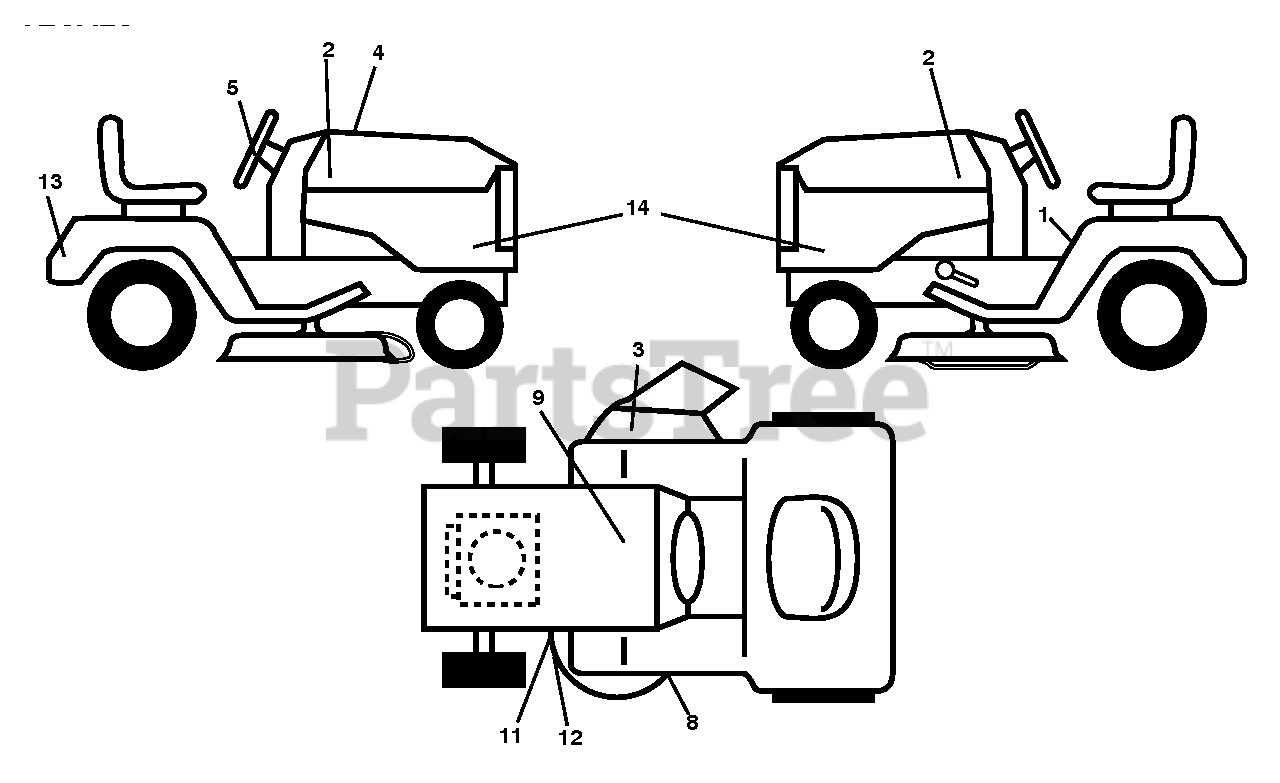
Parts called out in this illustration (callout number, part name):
1	DECAL.FENDER.WARNING.ENGLISH
2	DECAL.POULAN PRO.2015
3	DECAL, DECK DEFLECTOR, WARNING
4	DECAL DECAL.RPL.KH.KT7.TGW.54.
5	DECAL.STRWHL.BLK.2014.PPRO
8	DECAL.MOWER.SCH.48/54.PREM
9	DECAL BTRY SYMBOLS
11	DECAL.MOWER.CAUTION.TENSION.AR
12	DECAL.PPRO.10YRDECKWAR.POP
13	DECAL.REARFNDR.POULAN PRO.2015
14	DECAL.SDPNL.PB24VA54.BLK.PPRO
